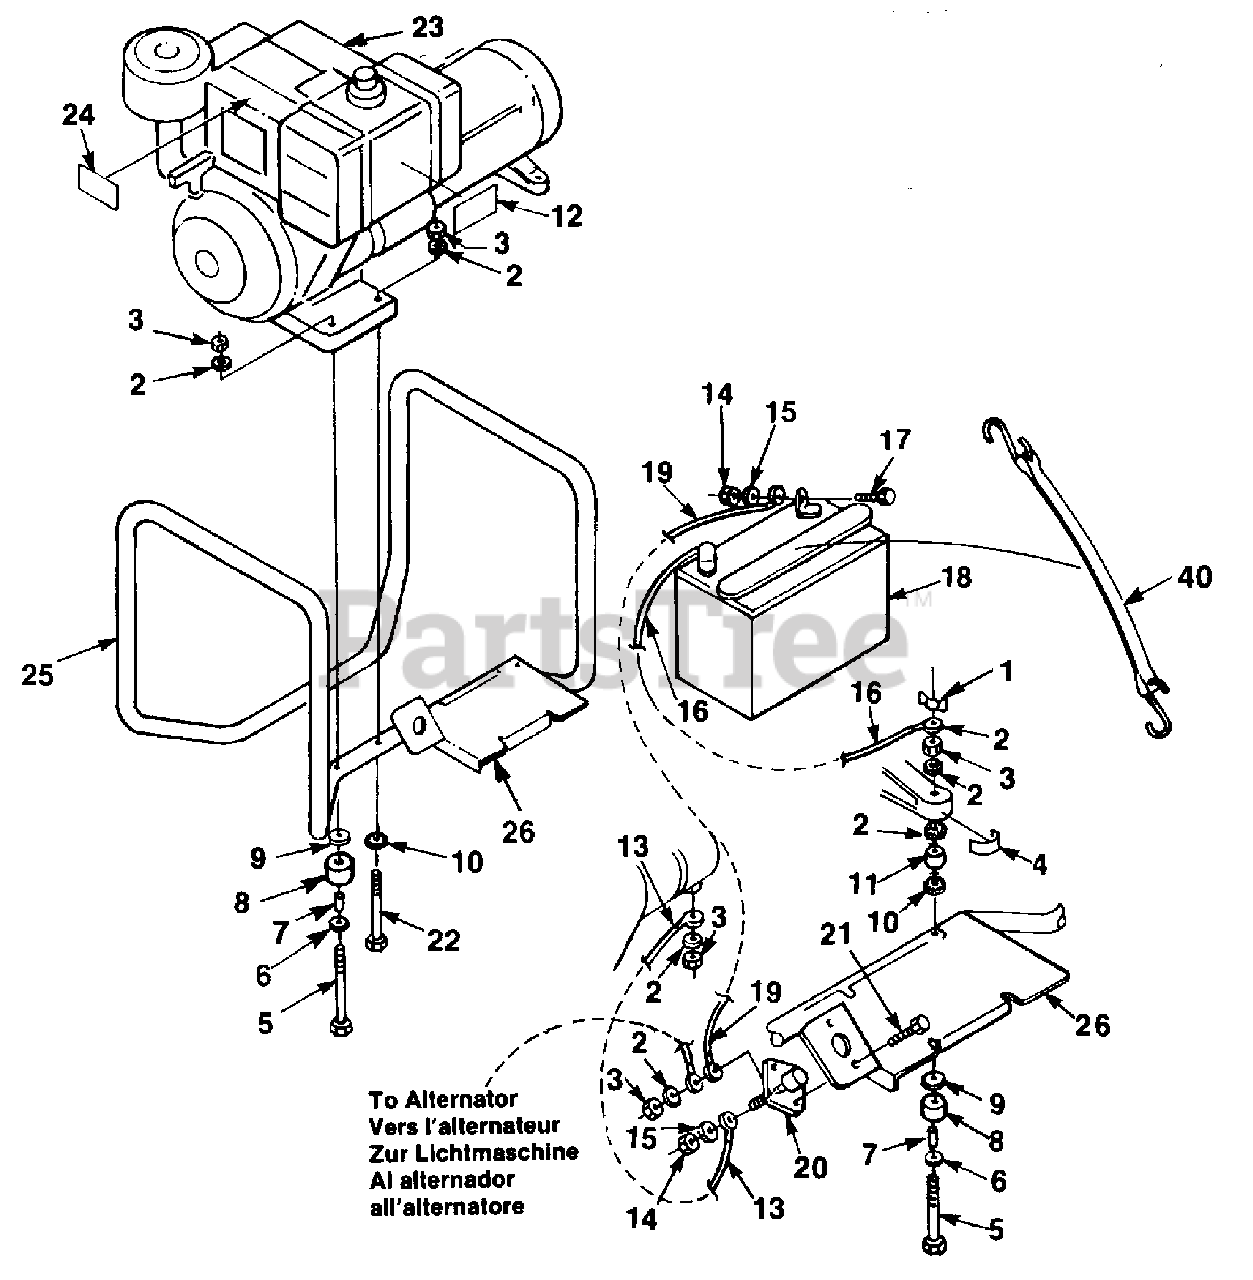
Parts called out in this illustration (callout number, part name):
1	NUT- Wing (5/16-18)
2	WASHER--Lock Int. (5/16")
3	NUT- Hex (5/16-18 STL)
4	DECAL- Ground
5	SCREW- Cap hex hd. (5/16-18 x 4") (Generator & Carburetor side)
6	WASHER- Flat (5/16")
7	SPACER- Foot
9	WASHER- Flat
10	WASHER- Lock int.
12	DECAL- Caution
13	CABLE- Battery (Red)
14	NUT- Hex
15	WASHER- Lock
16	CABLE- Battery (Black)
17	SCREW- (1/4-20 x .625")
18	BATTERY
19	CABLE- Battery (Red)
20	SWITCH- Starter
21	SCREW- Washer hex.
22	SCREW- (5/16-18 x 2 1/2")
23	ENGINE
24	DECAL- Warning
25	MEMBER- Frame (Engine)
26	MEMBER & BATTERY SUPPORT
40	STRAP- Hold down
